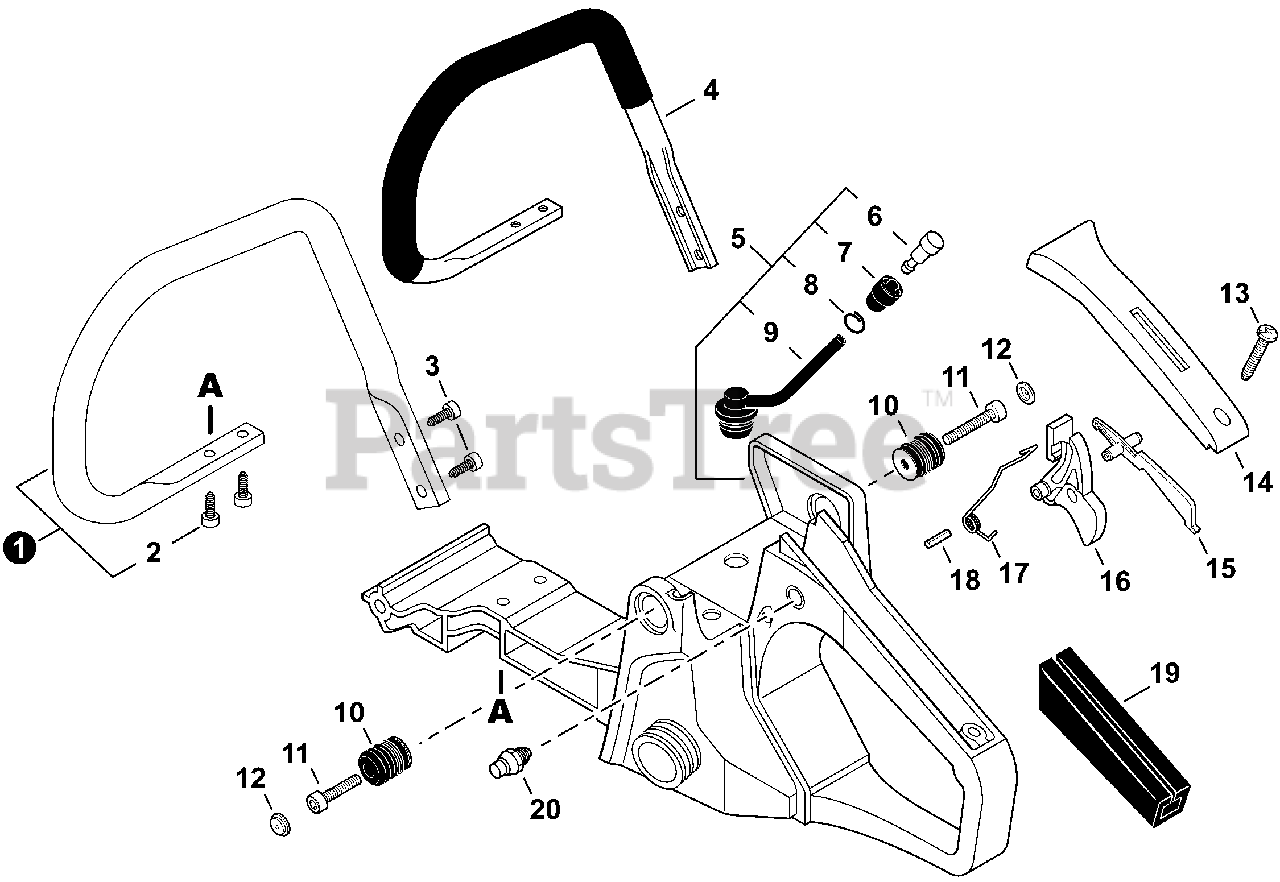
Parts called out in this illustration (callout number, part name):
1	HANDLE SET, FRONT - NYLON
2	SCREW TAPPING 5×20
3	SCREW TAPPING 5×20
4	HANDLE, FRONT - ALUMINUM
5	HANDLE ASSY, REAR
6	VENT ASSY
7	HOLDER, VENT
8	CLIP Ø6.5 MM
9	PIPE, VENT 3×6×65
10	CUSHION 4
11	BOLT 4×10×13.5
12	CAP, CUSHION
13	SCREW 4×14
14	COVER, HANDLE
15	LOCKOUT, THROTTLE
16	TRIGGER, THROTTLE
17	SPRING, TORSION
18	PIN, SPRING 4×30
19	GRIP, HANDLE
20	LOCK, THROTTLE TRIGGER
